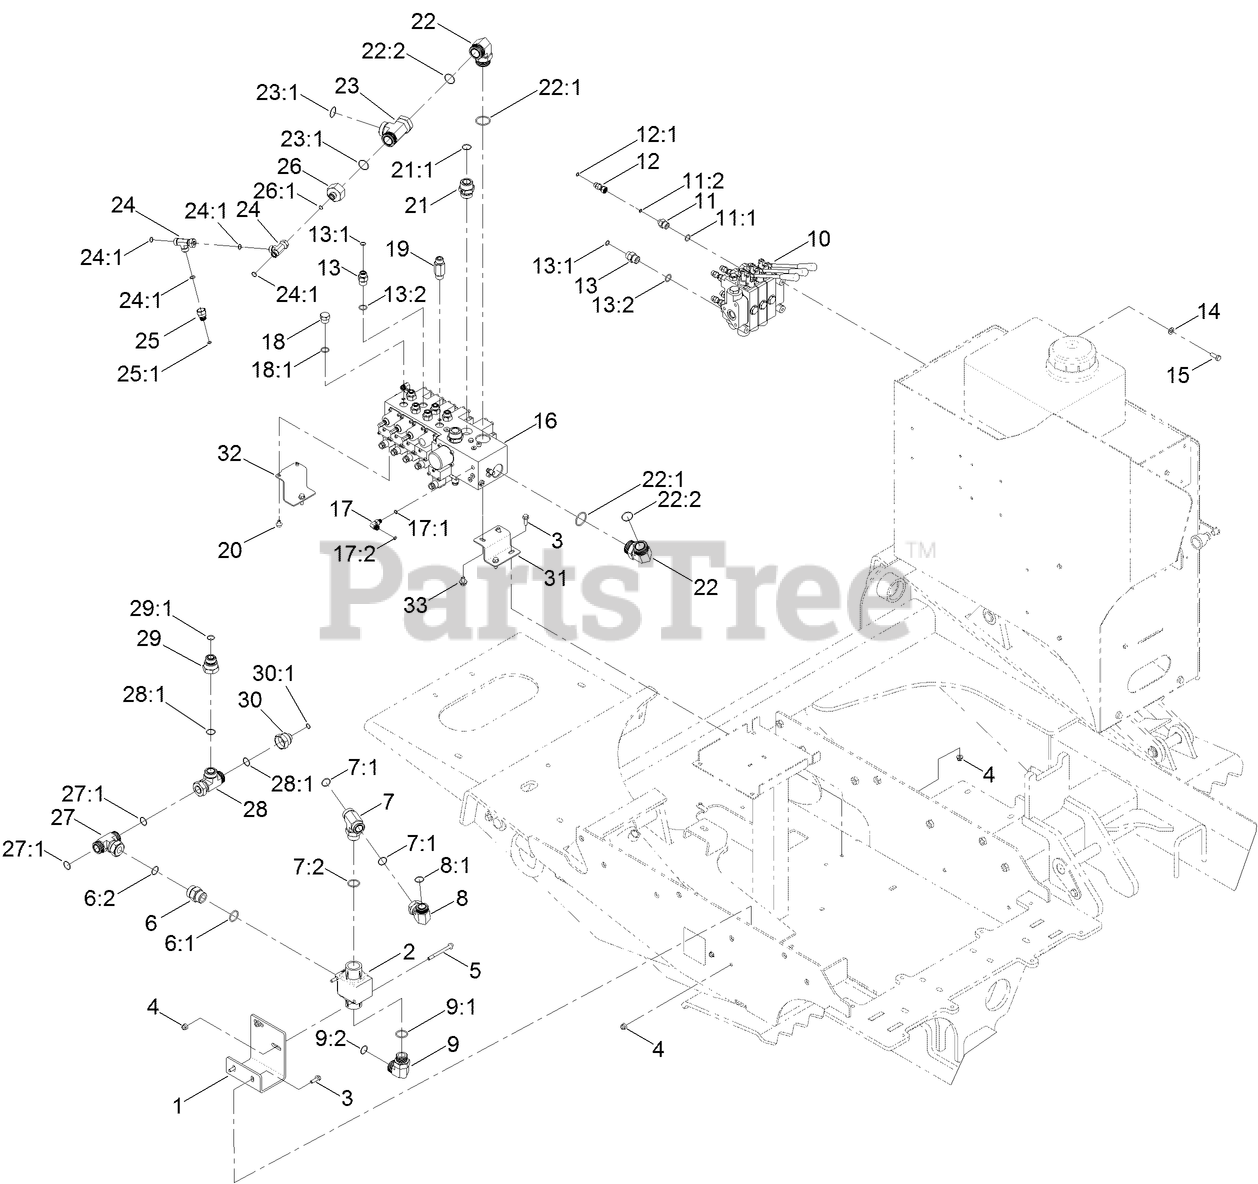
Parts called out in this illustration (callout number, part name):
1	PLATE-MOUNT, THERMAL BYPASS
2	VALVE-THERMOSTAT
3	SCREW-HHF
4	NUT-LOCK, HHF
5	SCREW-FLANGE
6	FITTING-STRAIGHT
6:1	O-RING
6:2	O-RING
7	FITTING-HYD
7:1	O-RING
7:2	O-RING
8	FITTING-SWIVEL, 90 DEG
8:1	O-RING
9	FITTING-ELBOW, 90 DEG
9:1	O-RING
9:2	O-RING
10	3 SPOOL HYD VALVE ASM
11	FITTING-STR
11:1	O-RING
11:2	O-RING
12	FITTING-STRAIGHT
12:1	O-RING
13	FITTING-STRAIGHT
13:1	O-RING
13:2	O-RING
14	WASHER-FLAT
15	SCREW-HH
16	5-SECTION HYD VALVE ASM
17	FITTING-90 DEG
17:1	O-RING
17:2	O-RING
18	PLUG-HH
18:1	O-RING
19	VALVE-CHECK, 30 PSI
20	SCREW-FLANGE
21	FITTING-STRAIGHT
21:1	O-RING
22	FITTING-ELBOW 90
22:1	O-RING
22:2	O-RING
23	FITTING-TEE, RUN
23:1	O-RING
24	FITTING-HYD, TEE
24:1	O-RING
25	FITTING-HYD
25:1	O-RING
26	FITTING-REDUCER
26:1	O-RING
27	FITTING-TEE
27:1	O-RING
28	FITTING-TEE
28:1	O-RING
29	FITTING-REDUCER
29:1	O-RING
30	FITTING-REDUCER
30:1	O-RING
31	BRACKET-FRONT, 5-SECTION VALVE
32	BRACKET-REAR, 5-SECTION VALVE
33	SCREW-HHF
